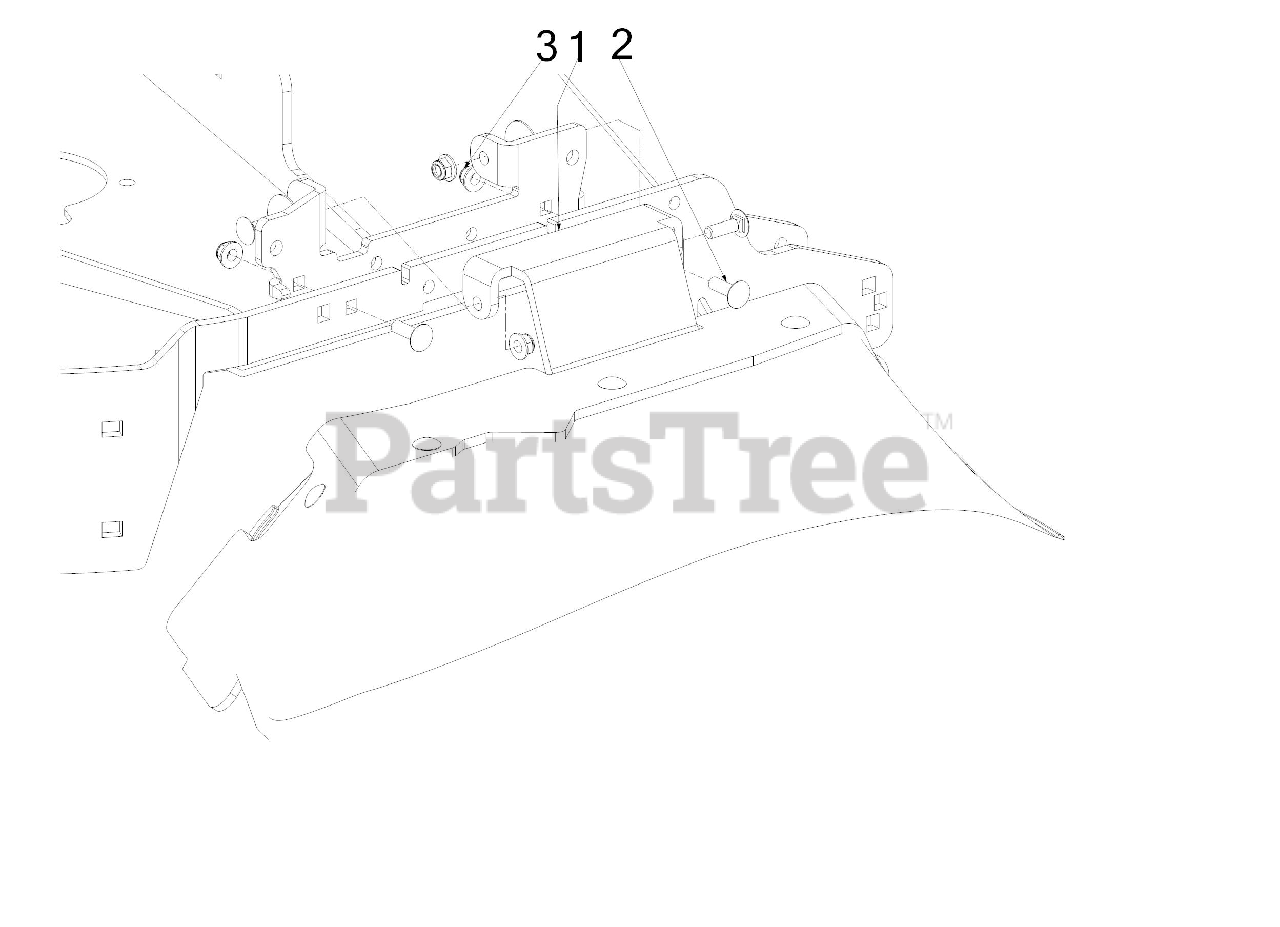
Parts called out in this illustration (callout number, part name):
1	72" DECK CHUTE ASSEMBLY
2	CARRIAGE BOLT 5/16-18 x 1.00
3	FLANGE LOCK NUT 5/16-18
